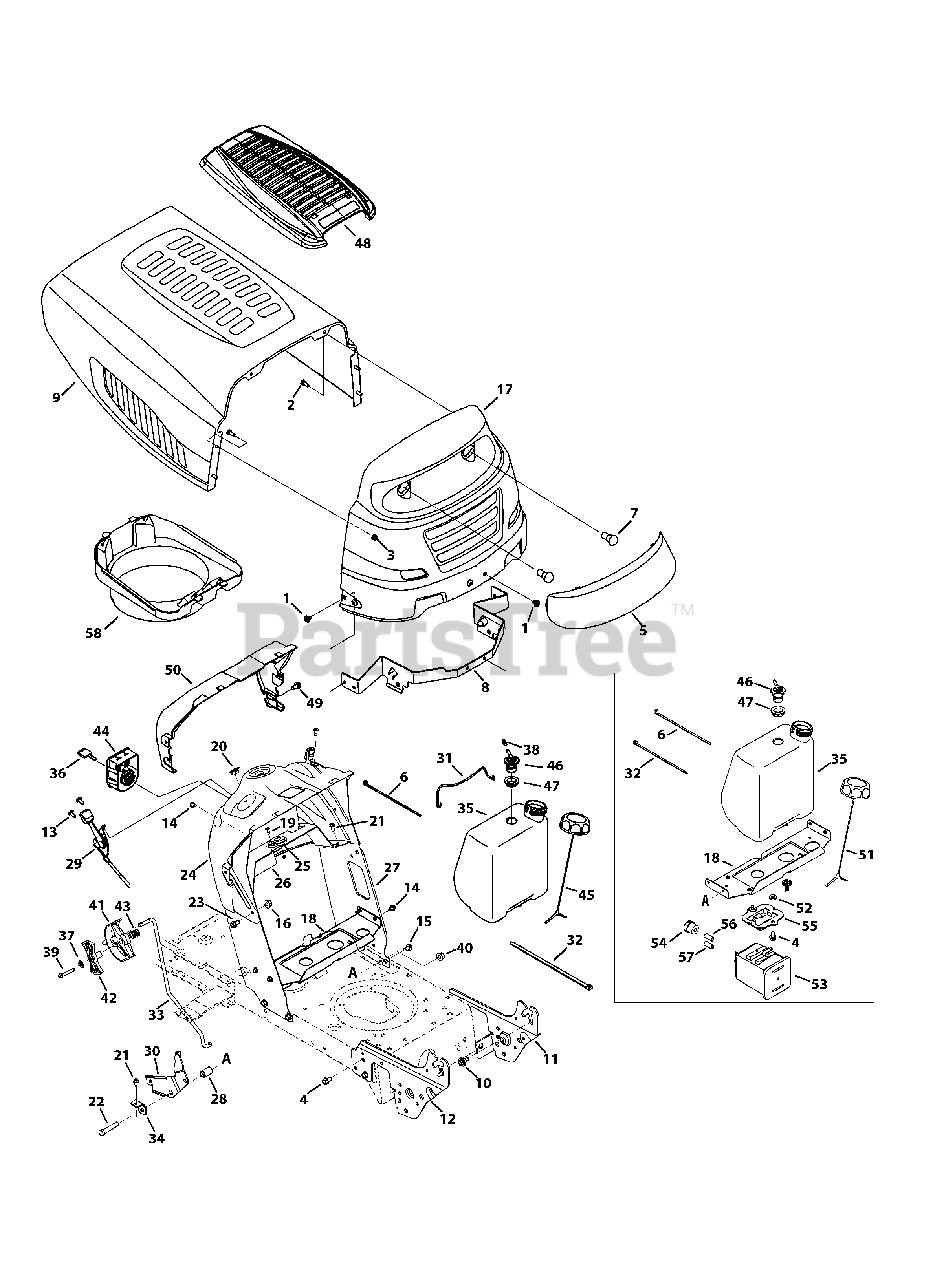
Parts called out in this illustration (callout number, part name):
1	Screw, 5/16-18 x .375
2	Hex Screw, 1/4-20 x .620
3	Flangelock Nut, 1/4-20
4	Screw, 5/16-18 x .750
5	Grill Lens
6	Cable Tie
8	Hood Pivot Bracket
10	Shoulder Screw, 5/16-18 x .43 x .29
11	Left Support Pivot Bracket
12	Right Support Pivot Bracket
13	Screw, 1/4-20 x .500
14	Screw, 1/4-20 x .500
15	Screw, 5/16-18 x .625
16	Flangelock Nut, 5/16-18
17	Grill
18	Gas Tank Support Bracket
19	Screw, #10-16 x .500
20	Choke Plug
21	Tap Screw, 1/4-20, 0.625
22	Hex Screw, 3/8-16 x 2.0
23	Hex Screw, 5/16-18 x .625
24	Dash, Upper
25	Bearing, .628 ID x 1.36
26	Bracket, Steering Support
27	Dash, Lower
28	Flange Spacer, .390 x .671 x 1.095
29	Throttle/Choke Cable
30	Speed Latch - No RMC
31	Battery Assembly Rod
32	Cable Tie
33	Speed Control Rod
34	Speed Latch Tab
35	1.36 Gallon Fuel Tank
36	Key, Assembly
37	Lock Washer, 1/4
38	Hose Vent, 3/16 EPA
39	Hex Washer Screw, 1/4-20 x 1.50
40	Flangelock Nut, 3/8-16
41	Shift Lever
42	Index Control
43	Compr. Spring, .72 OD x .78
44	3 Position Key Switch
45	Fuel Cap, 2.25"
46	Rollover Valve
47	Rubber Grommet, 23 x 3.55
48	Hood Scoop
49	Screw, 1/4-15 x .750
50	Dash Collar
51	Fuel Cap, 2.25"
52	Flat Washer, .344 x .750 x .120
53	5 Gallon Carbon Canister
54	Vent Filter Canister
55	Canister Adaptor Bracket
56	Hose, Fuel, Low Perm., White
57	Hose, Fuel, Low Perm., Yellow
